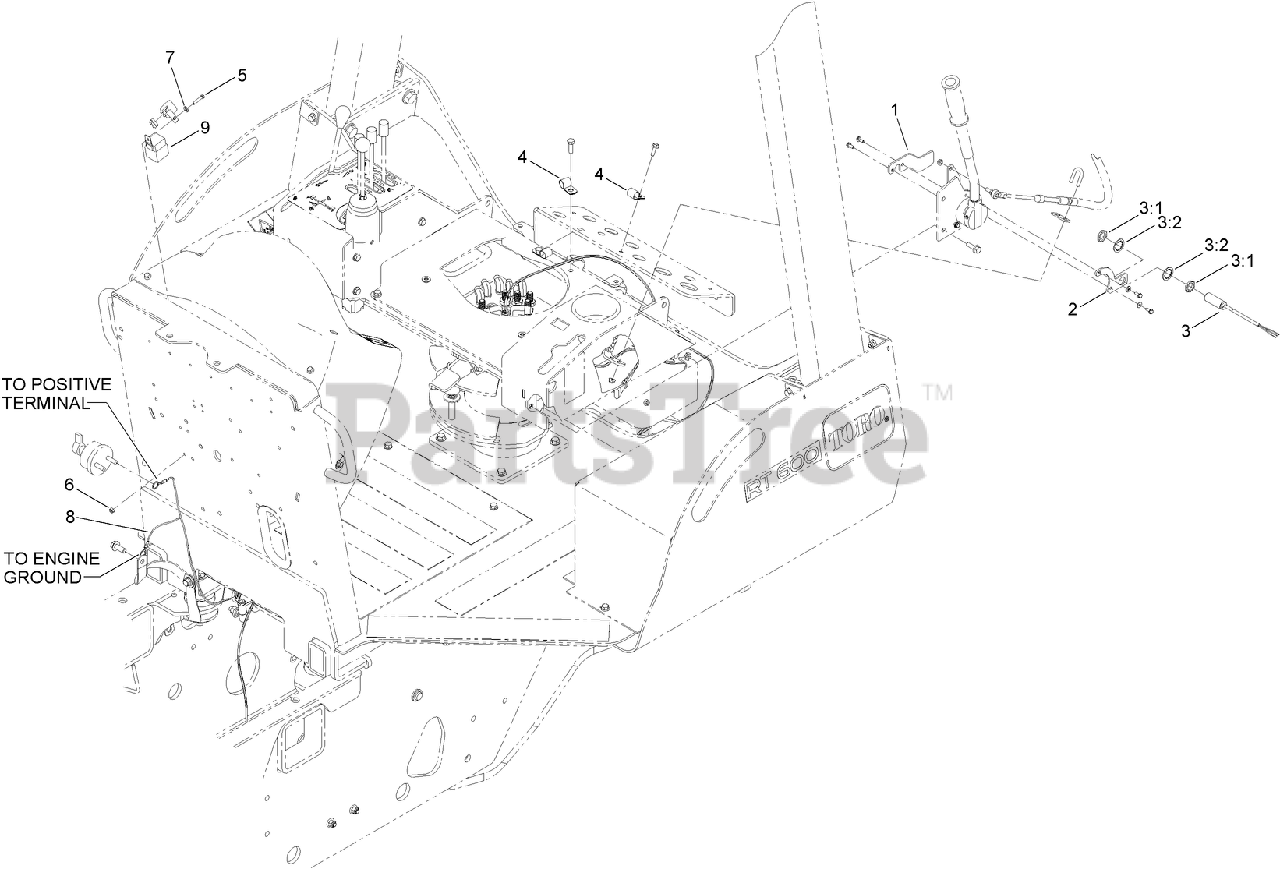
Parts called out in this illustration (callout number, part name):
1	PLATE-LINKAGE
2	PLATE-MOUNT
3	PROXIMITY SWITCH ASM
3:1	NUT-HEX
3:2	WASHER-LOCK, INTERNAL TOOTH
6	NUT-LOCK, NI
7	WASHER-FLAT
8	HARNESS-BACKUP ALARM
9	RELAY
